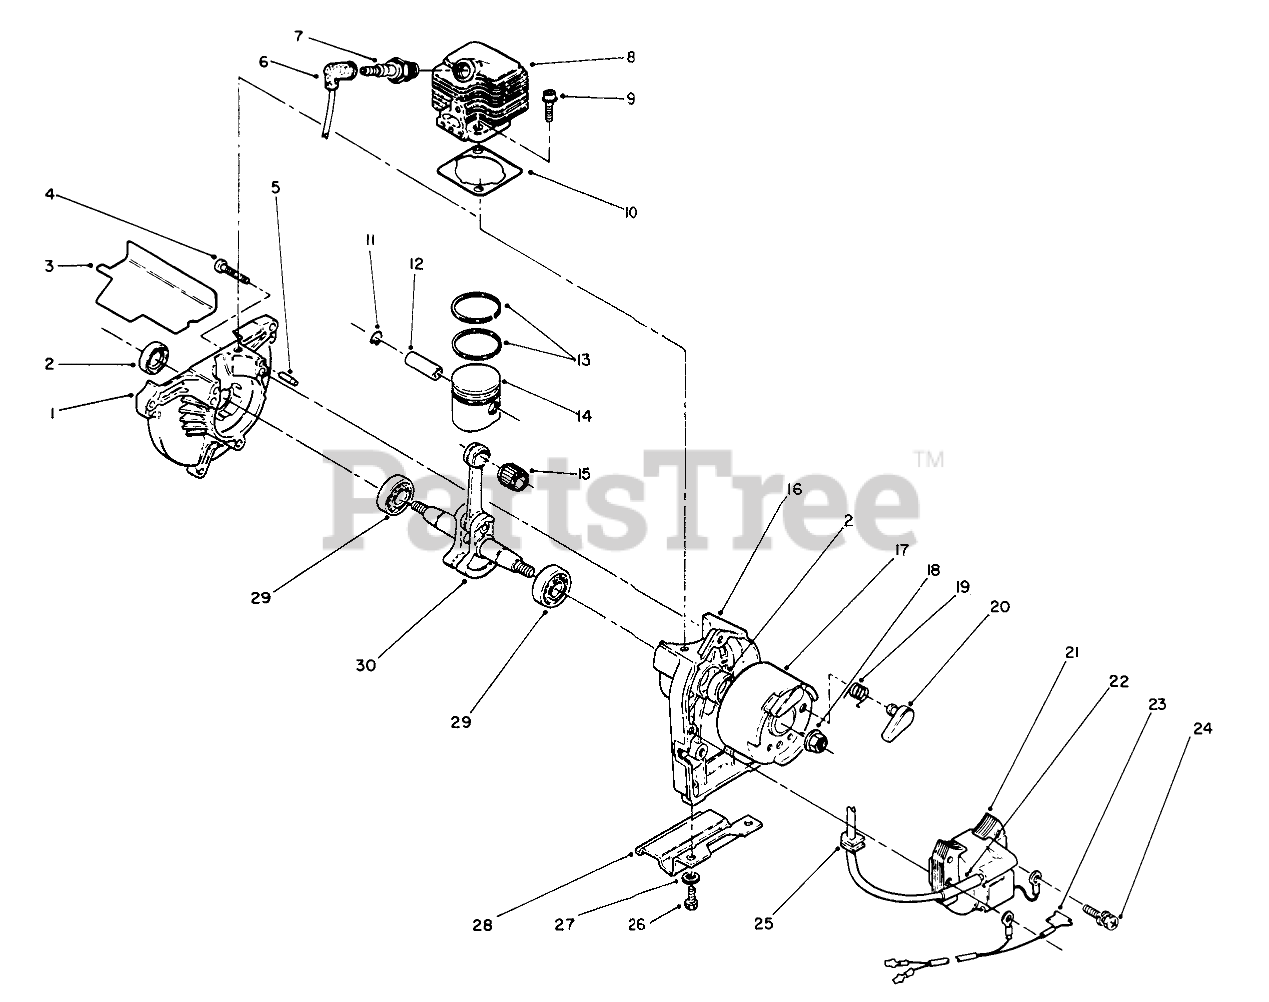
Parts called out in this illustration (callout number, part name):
1	Case-Drive
2	OIL SEAL
3	BAFFLE GASKET
4	Screw
6	PLUG BOOT
7	Plug-Spark
8	CYLINDER
9	FLANGE BOLT
10	CYL GASKET
11	PISTON PIN CLIP
12	PISTON PIN
13	TOP RING
14	Piston Ass-y (Incl. Ref. #12)
15	NEEDLE BEARING
16	STARTER CASE
17	Flywheel (Incl. Ref. #19 & 20)
19	RETURN SPRING
20	RATCHET
21	IGNITION COIL
23	LEAD WIRE
24	BOLT AND WASHER
25	GROMMET
26	M6 X 1 X 1/2 MWH SCREW
27	WASHER-LOCK
28	STAND SUPPORT
29	BEARING
30	CRANKSHAFT ASSEMBLY
